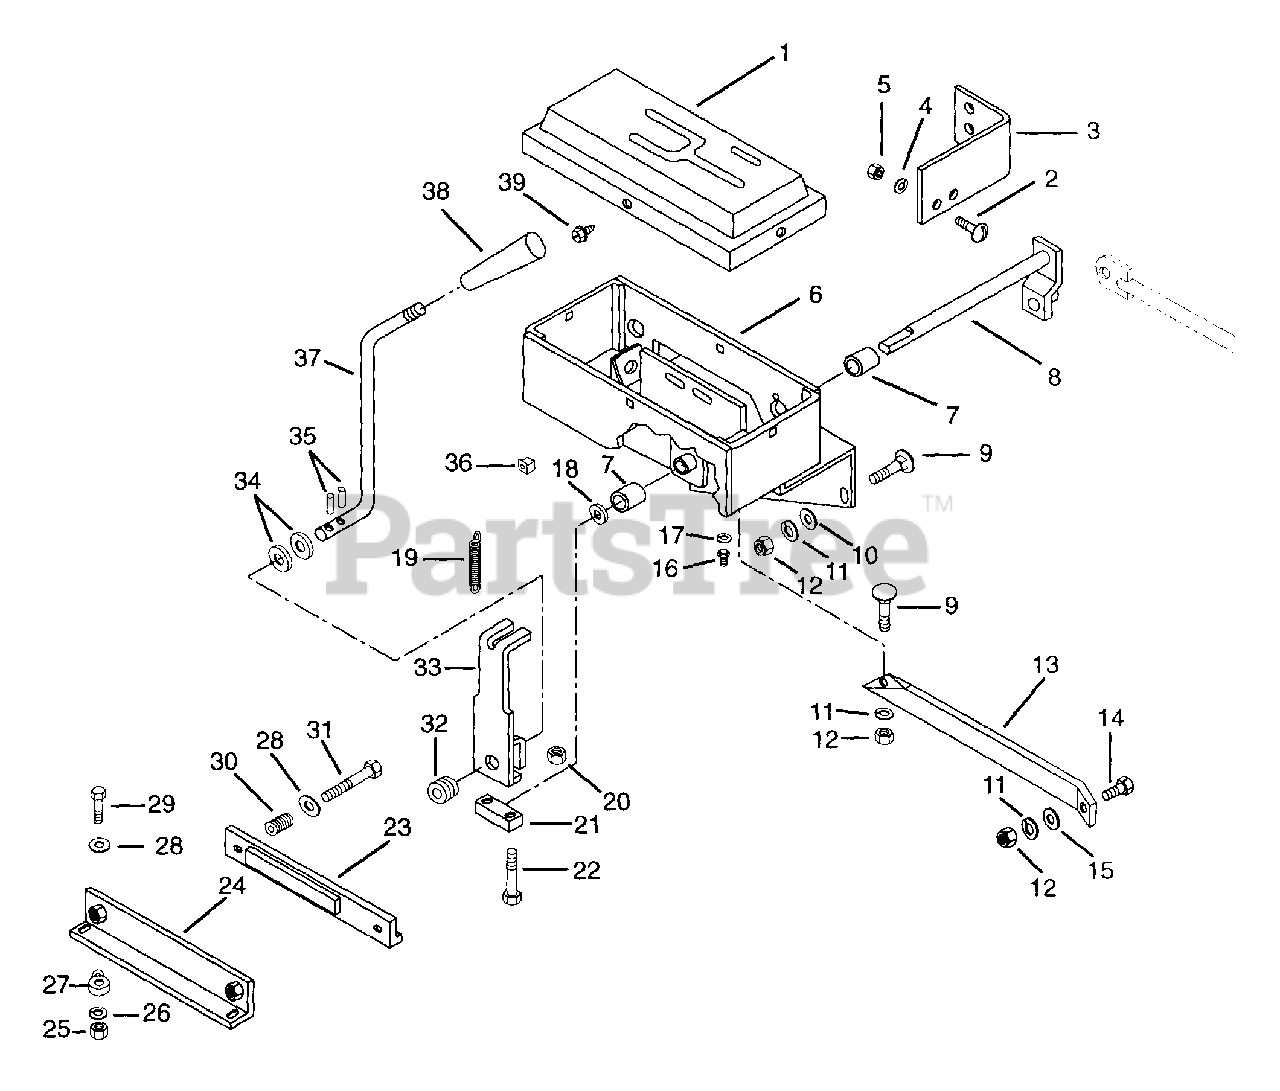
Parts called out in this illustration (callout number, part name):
1	CONTROL CONSOLE COVER W/DECAL
2	SCR-MCH 10-24X.50 SLRH PL
3	BRACKET - SWITCH
4	WSHR-LK 10X.047 MED PL
5	NUT-HEX 10-24 PL
6	CONTROL BOX
7	BSHG-SLV .625X.750X1.000
8	SHIFT SHAFT
9	BLT-RDHDSQSHNK .38-16X1.00 PL
10	WSHR-FL-STL .438X1.0X.083 PL
11	WSHR-LK .375X.094 MED PL
12	NUT-HEX .375-16
14	BLT-HEX .38-16X.75 PL GR2
15	WSHR-FL-STL.406X.812X.065PL
16	FTG-LUBE .25-28X.256 YWZC
17	WSHR-LK .250X.047 LT PL
18	WSHR-FL-STL .630X1.005X.062 PL
19	SG-TENS .072X.565X1.87
20	NUT-LK-TOP .312-18 GR C PL
22	BLT-HEX .31-18X1.50 PL GR5
23	L. H. FRICTION BRAKE
24	R.H. FRICTION BRAKE
25	NUT-HEX .312-18
26	WSHR-LK .312X.097 PL HVY
27	SPACER .344X.750X.625X.500
28	WSHR-FL-STL .323X.625X.062 PL
29	BLT-HEX .31-18X1.25 PL GR2
30	SG-COMP .093X.59X1.50
31	SCR-MCH .31-18X2.75 SLRH PL
32	GROMMET .438ID X .688 OD
34	WSHR-FL-STL .520X.827X.062 YZ
35	PIN-ROLL .188X.88
36	PLASTIC GROMMET
37	SHIFT ROD
39	SCR-TAP 10-12X.50 CRPH PL A
